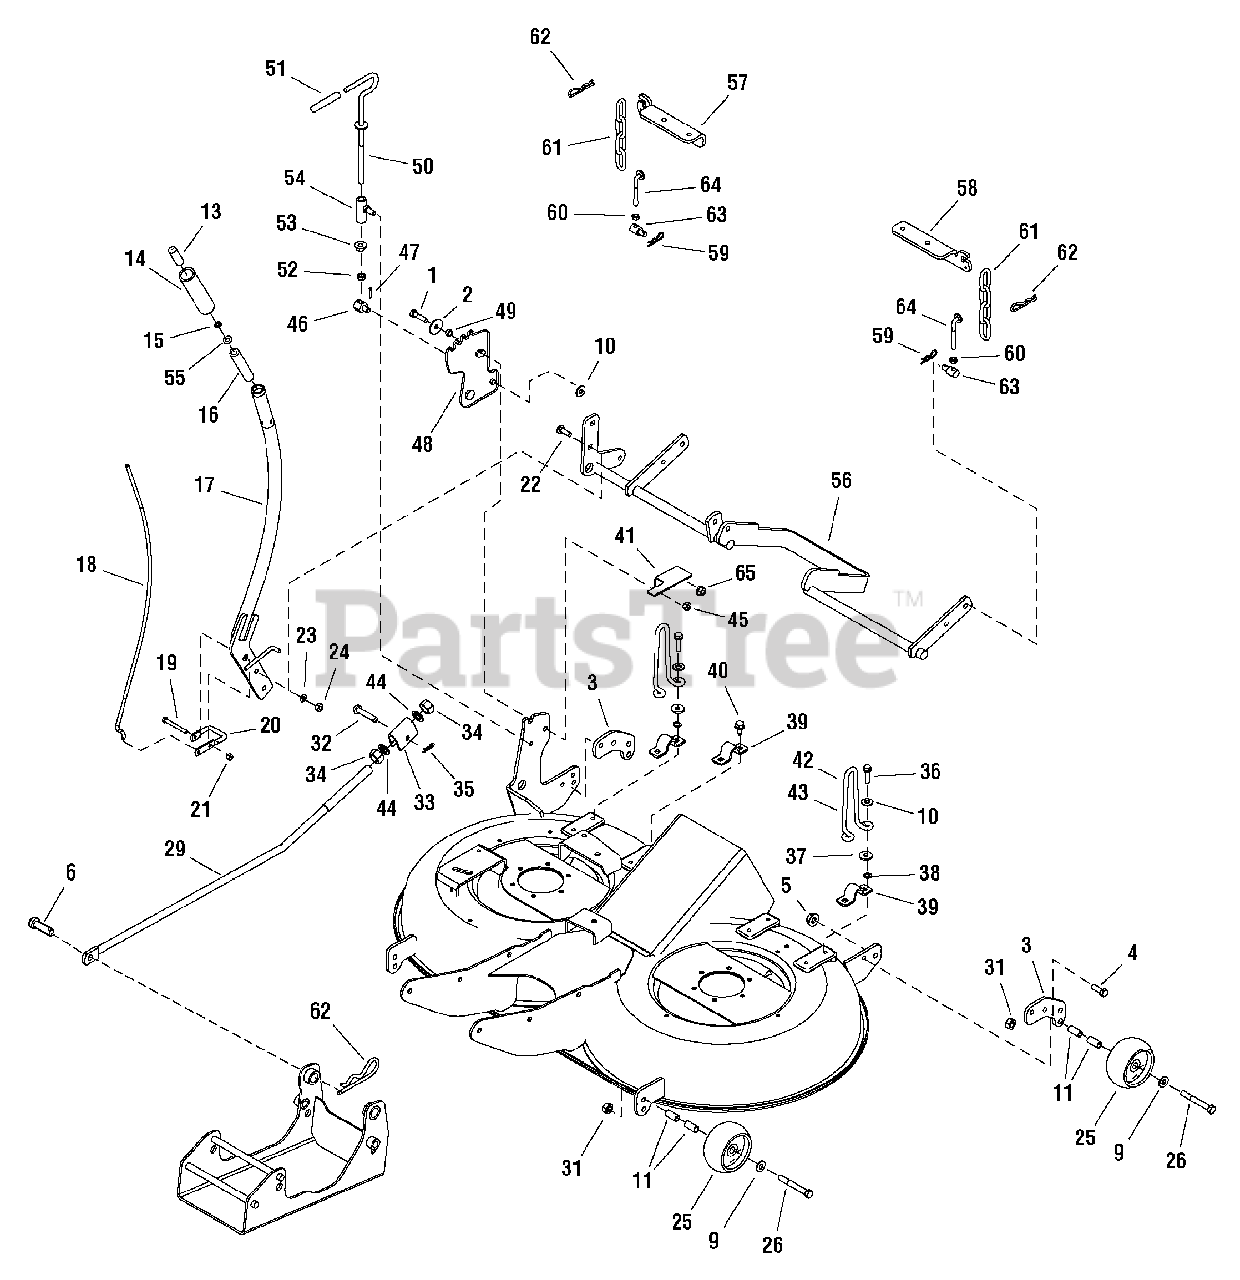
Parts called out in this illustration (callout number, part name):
1	CAPSCREW, Hex Head 5/16-18 x 1-1/4 G5
2	WASHER, 5/16
3	BRACKET, Flat Mounting
4	CAPSCREW, Hex Head 5/16-18 x 1 G5
5	NUT, Hex Flange 5/16-18 Esna
6	PIN, Clevis
9	WASHER, Flat. .5
10	WASHER, 3/8
11	NUT, Flange, 3/8-16
13	BUTTON
14	GRIP
15	NUT, Push Pal 1/4 Diameter Thread
16	SPRING, Compression
17	HANDLE ASSEMBLY, Lift Curved
18	ROD, Curved
19	CAPSCREW, Hex Head 1/4-20 x 2-1/4 G5
20	LATCH
21	NUT, Hex Lock Esna Light 1/4-20
22	BOLT, Carriage, Short Neck, 5/16-18 x 1
23	LOCKWASHER, 5/16
24	NUT, Hex 5/16-18
25	WHEEL
26	CAPSCREW, Hex Head 3/8-16 x 3 G5
29	ROD
31	NUT, Hex Toplock Spiralock Flange 3/8-16
32	PIN, Round Head Drilled 3/8 x 2
33	TRUNNION
34	NUT, Hex 5/8-11
35	PIN, Quick
36	SCREW, Hex Washer Head Taptite 5/16-18 x 1-1/4
37	WASHER, 5/16
38	NUT, Push Pal 5/16 Diameter Thread
39	STRAP, Rocker Shaft
40	SCREW, Hex Washer Head Taptite 5/16-18 x 3/4
41	BRACKET, Height of Cut
43	UPSTOP
44	WASHER, 5/8
45	NUT, Hex Lock ESNA Light, 5/16-18
46	PIVOT, 3/4 Hex & 3/8
47	PIN, Cotter 3/4
48	BRACKET, Adjusting
49	SPACER
50	ROD & WASHER ASSEMBLY
51	GRIP
52	NUT, Hex Jam 3/8-16
53	NUT, Hex Flange 3/8-16
54	GUIDE ASSEMBLY, Rod
55	WASHER, 5/16
56	SHAFT ASSEMBLY, Rocker 40"
57	HANGER, R.H.
58	HANGER, L.H.
59	CLIP, Hair Pin
60	NUT, Hex Jam 5/16-18
61	CHAIN, Link
62	CLIP, Hair Pin
63	TRUNNION
64	ROD, Height Adjusting
65	NUT, Hex Flange 3/8-16 Two-Way Lock
